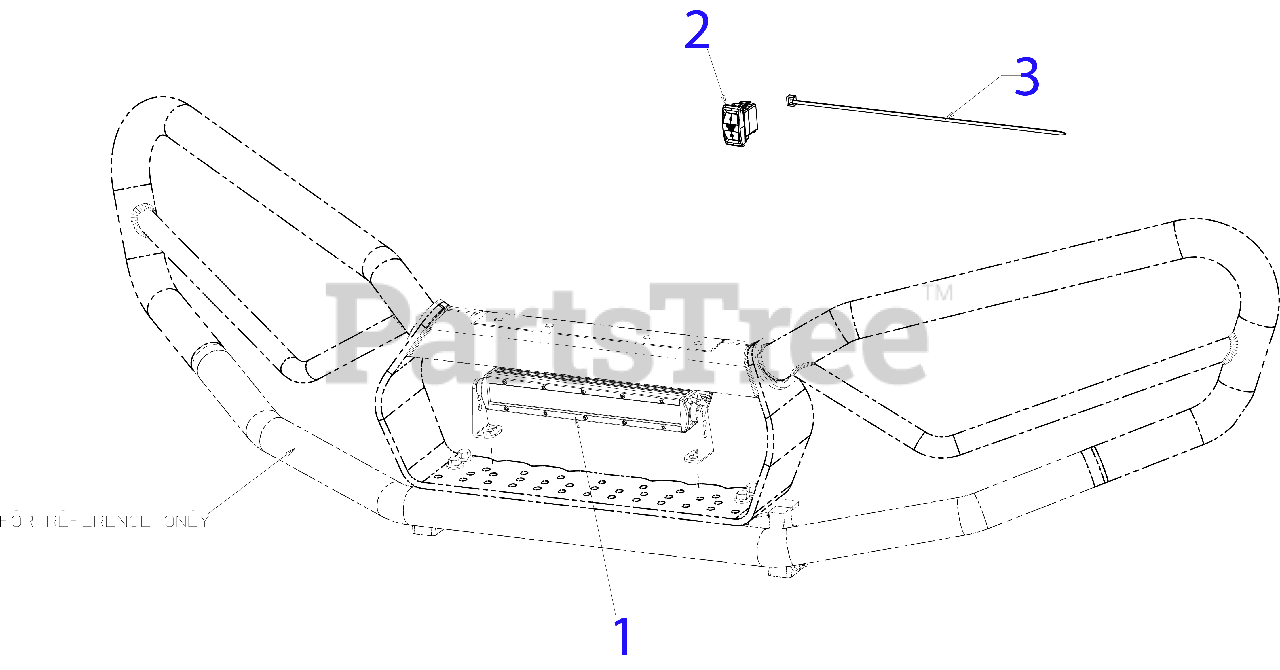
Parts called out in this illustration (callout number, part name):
1	LED FLOOD / SPOT LIGHT COMBO
2	ROCKER SWITCH FOR LIGHT BAR
3	TIE:CBL:14.5" LONG
